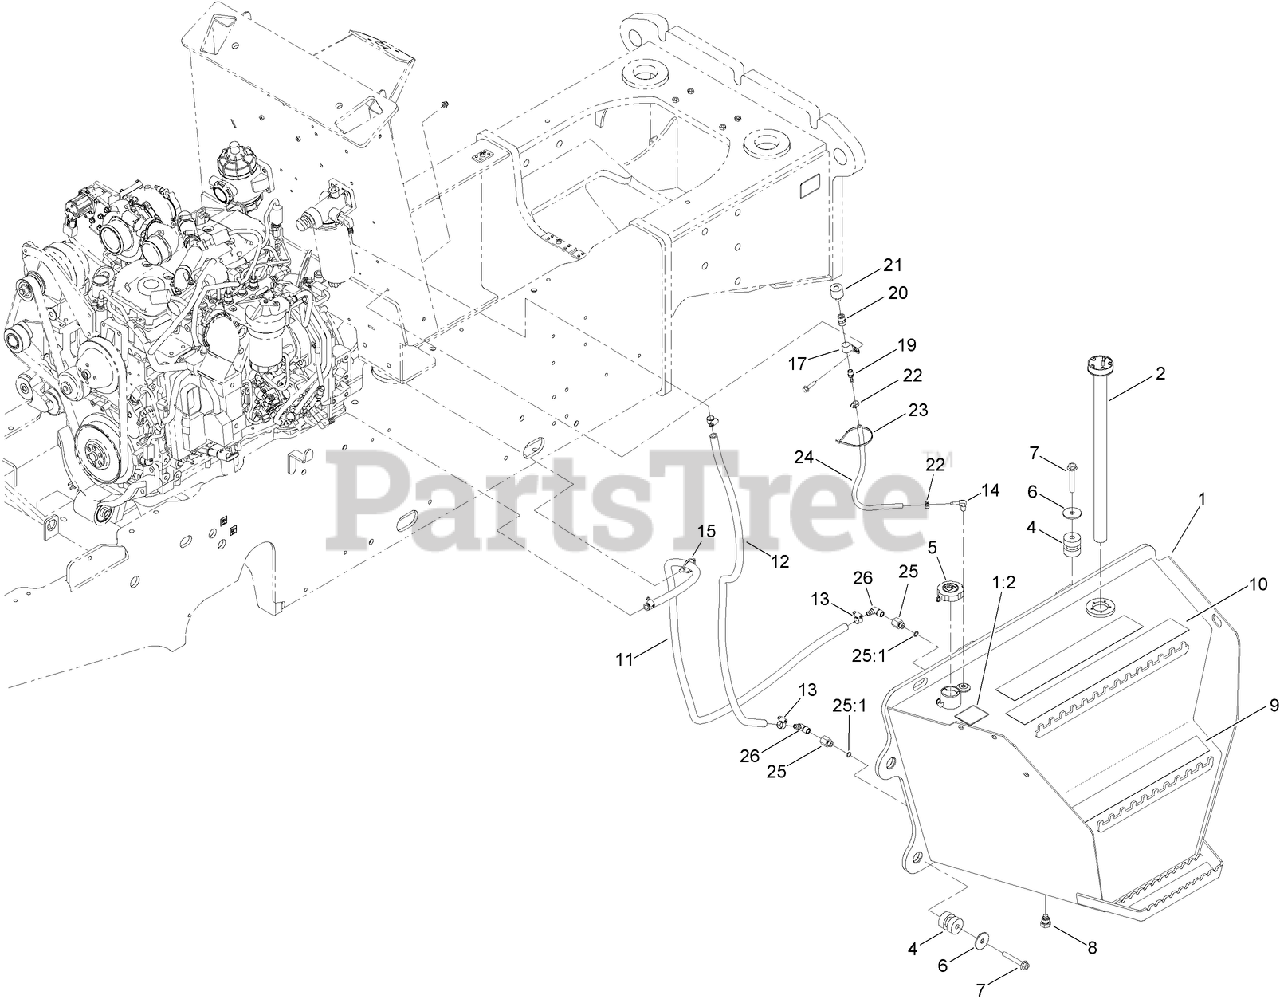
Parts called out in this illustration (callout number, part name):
1	FUEL TANK ASM
1:2	DECAL-DIESEL, ULTRA-LOW
2	SENDER-FUEL
4	ISOLATOR-MOUNTING, UNIVERSAL
5	CAP-DIESEL FUEL, NON-VENTED
6	WASHER-FLAT
7	SCREW-HHF
8	PLUG-HEX, MAGNETIC
9	TAPE-ANTI SKID, LOWER STEP
10	STRIP-ANTI SKID
11	HOSE-FUEL
12	HOSE-FUEL
13	CLAMP-HOSE, WORM DRIVE
14	STEM-90 (BARB HOSE)
15	CLIP-TIE
17	CLAMP-R
19	FITTING-STRAIGHT
20	COUPLING-PIPE (NPTF)
21	BREATHER
22	CLAMP-WORM
23	TIE-CABLE
24	HOSE-FUEL
25	FITTING-STRAIGHT
25:1	O-RING
26	ELBOW-90 DEG
